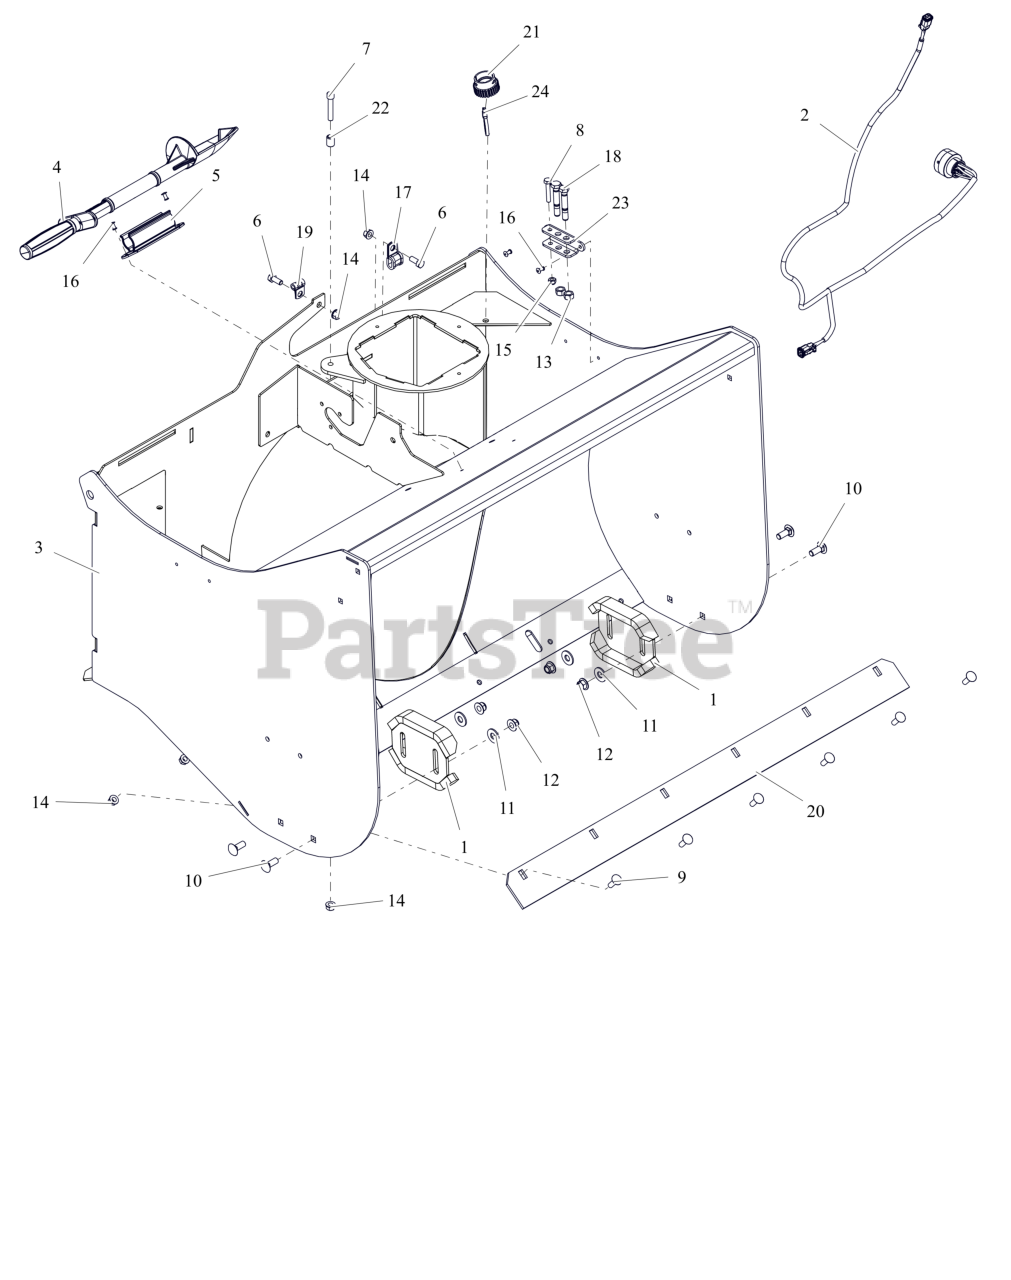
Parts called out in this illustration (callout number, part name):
1	RUNNER, SKID SHOE
2	HARNESS, BLOWER
3	WLDMT, HOUSING 36" - W/DECAL
4	DEVICE, SNOW CLEAN OUT
5	MOUNT, SNOW CLEAN OUT
6	BLT,HEX .31-18X.75 G5 ZCC
7	SCR, SKH .312-18X1.750 GR8 ZC120
8	BLT, HEX 0.25-28X1.5 G5 ZCC
9	BLT,RHSN .31-18X1.00 G5 ZCC
10	BLT, RHSN .38-16X1.00 G5 ZCC
11	WSHR,FLT .438X1.00X.083 ZCC
12	NUT,NYL-FLG .38-16 GF ZCC
13	NUT-LK-CTR .38-16 ZC120
14	NUT,LK-CTR-FLG .31-18 GF ZCC
15	NUT, NYL .25-28 ZCC
16	RVT-POP.187X.527 DOME ST
17	CLAMP, DOUBLE 5/16", 3/8" MNT
18	BOLT, SHEAR - .375-16 X 2.220
19	CLAMP, CABLE .250"
20	EDGE, CUTTING, 36" BLOWER
21	CAP, CONNECTOR - AHDC04-18
22	TUBE, ROUND .328 x .500 x .690
23	HOLDER, SHEAR BOLT - MAMMOTH
